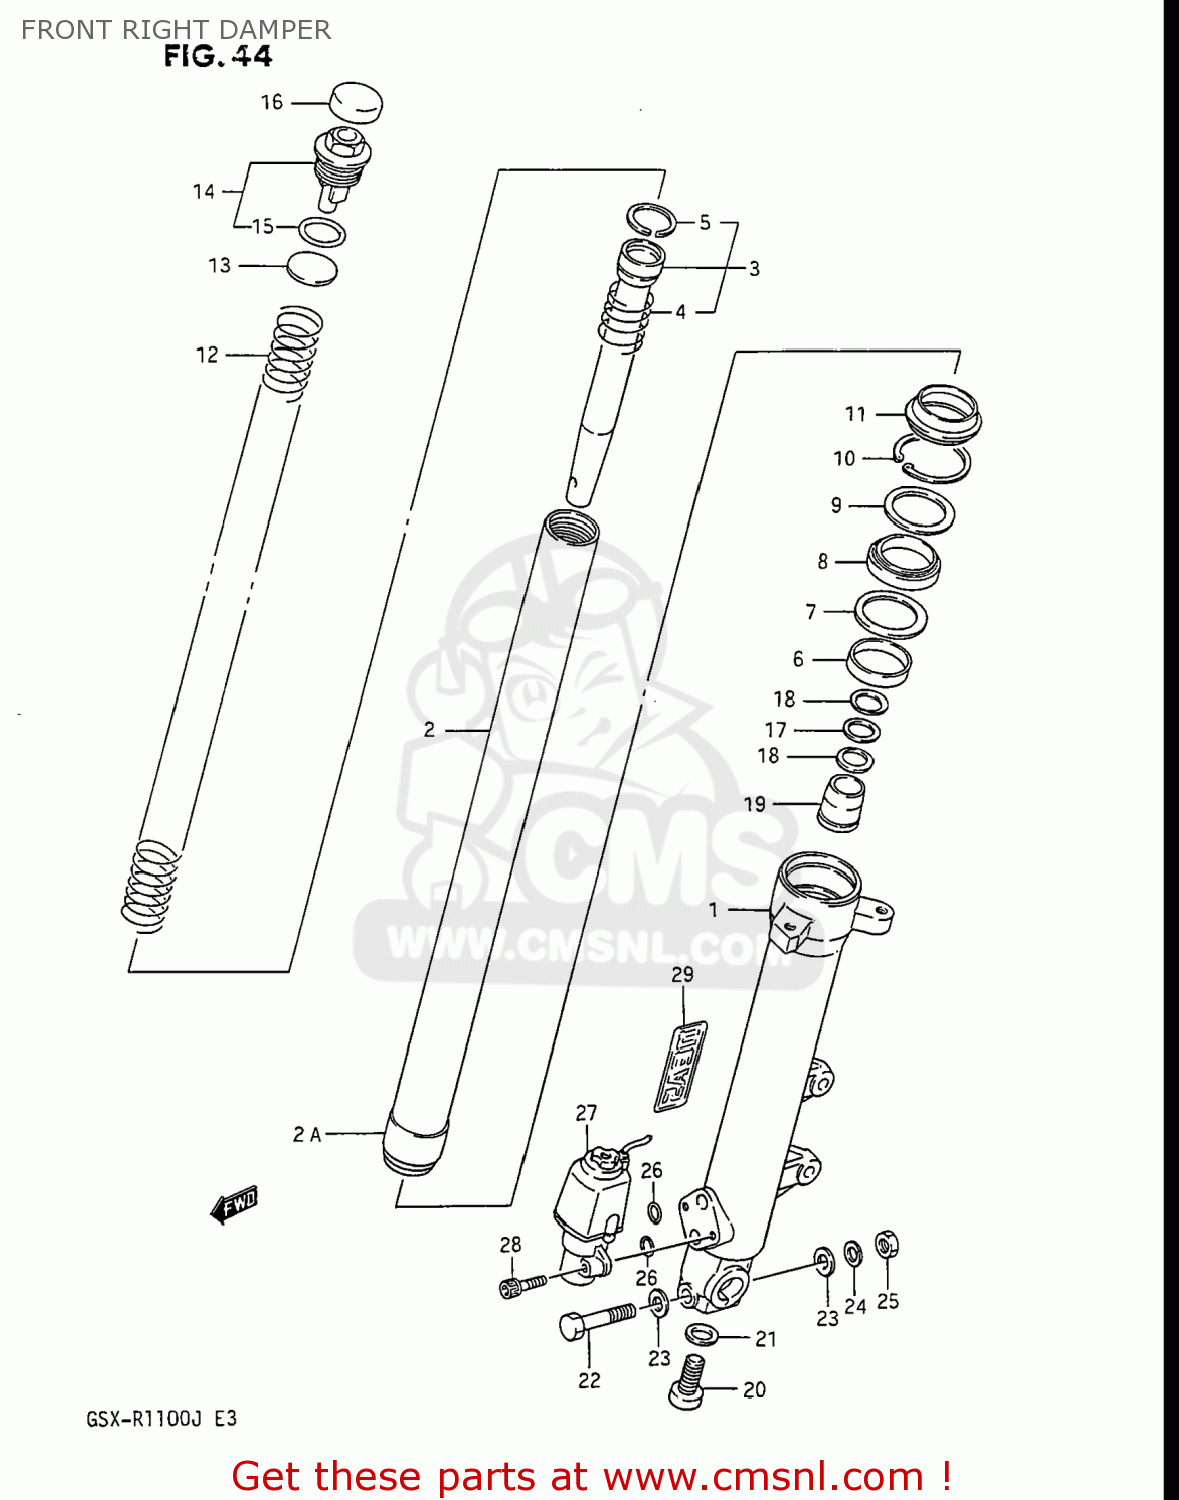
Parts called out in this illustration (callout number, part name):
1	TUBE,OUTER,RIGHT
2	TUBE,INNER
2A	METAL,SLIDE FR FORK
3	CYLINDER
4	SPRING,REBOUND
5	RING,FR FORK PISTON
6	METAL,SLIDE
7	WASHER,FORK OIL SEAL
8	OIL SEAL,FRONT FORK
9	WASHER,FORK OIL SEAL
10	RING,OIL SEAL STOPPER
11	DUST SEAL,FRONT FORK
12	SPRING
13	WASHER,FR FORK SPRING
14	CAP,FORK INNER TUBE
15	O RING
16	CAP,FORK INNER TUBE
17	WASHER,OIL LOCK PIECE
18	SPRING,FORK OIL LOCK PIECE
19	PIECE,OIL LOCK
20	BOLT(14X25)
21	GASKET (NAS)
22	BOLT 10X60
23	WASHER
24	LOCK WASHER
25	NUT
26	O RING
27	EAND ASSY
28	BOLT
29	EMBLEM
